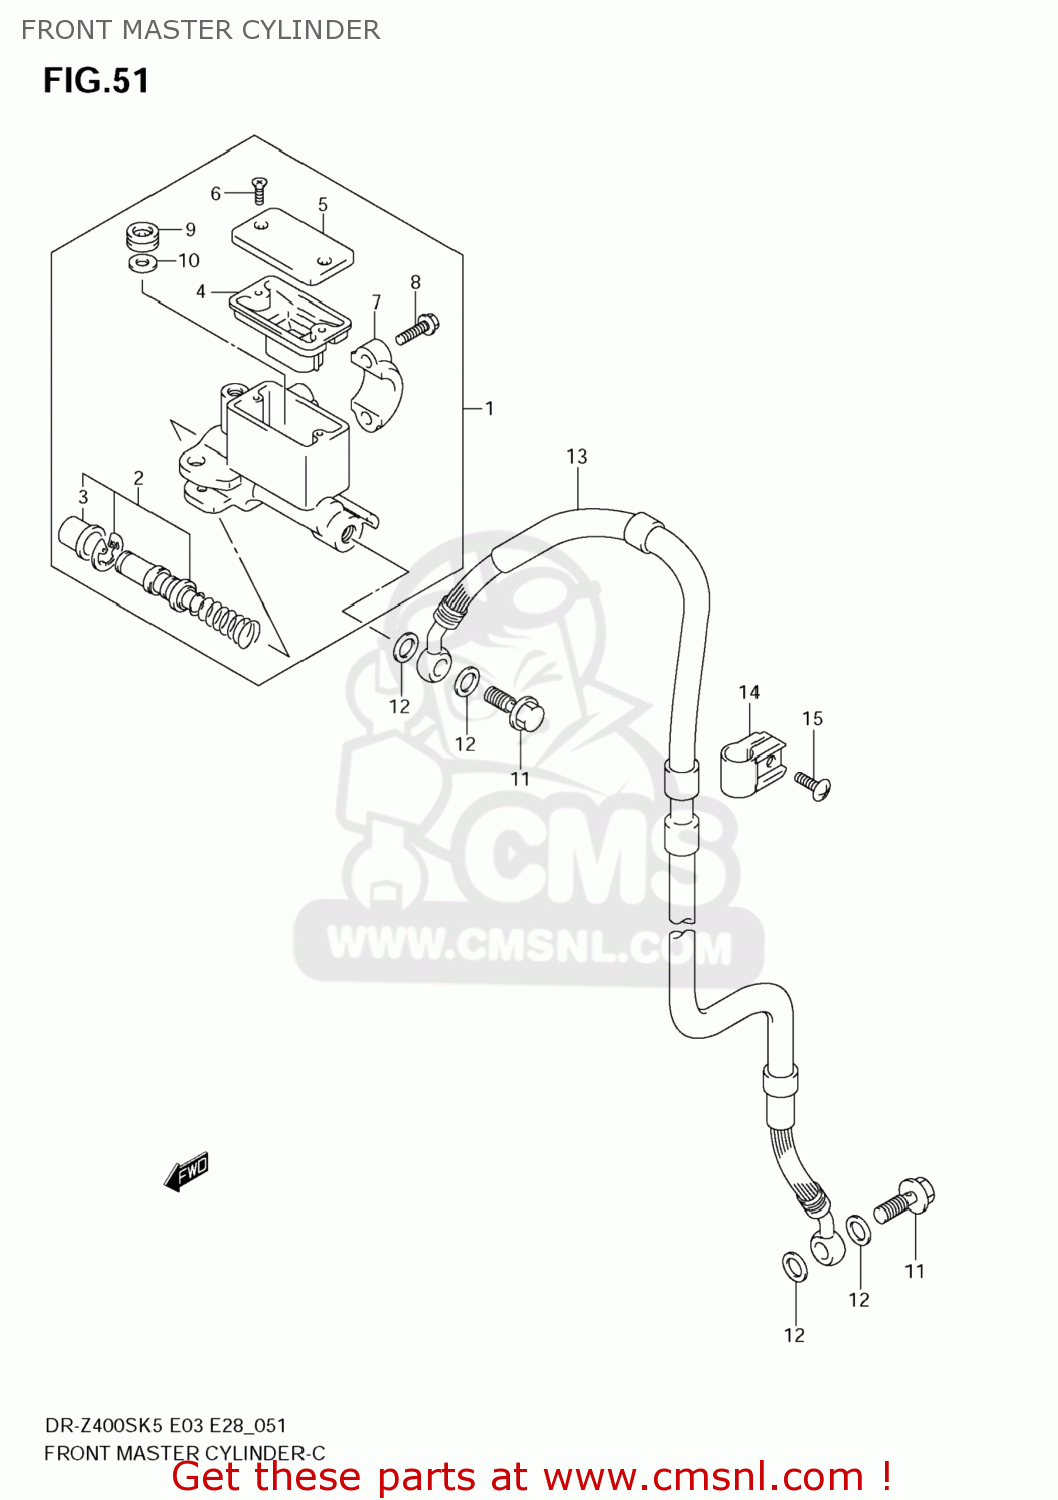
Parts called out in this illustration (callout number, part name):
1	CYLINDER ASSY,FR MASTER
2	PISTON/CUP SET
3	BOOT
4	DIAPHRAGM
5	CAP
6	SCREW
7	HOLDER
8	BOLT
9	SEPARATOR
10	RING
11	BOLT UNION
12	WASHER(10X15X1.5)
13	HOSE,FR BRAKE
14	CLAMP,BRAKE HOSE
15	SCREW
